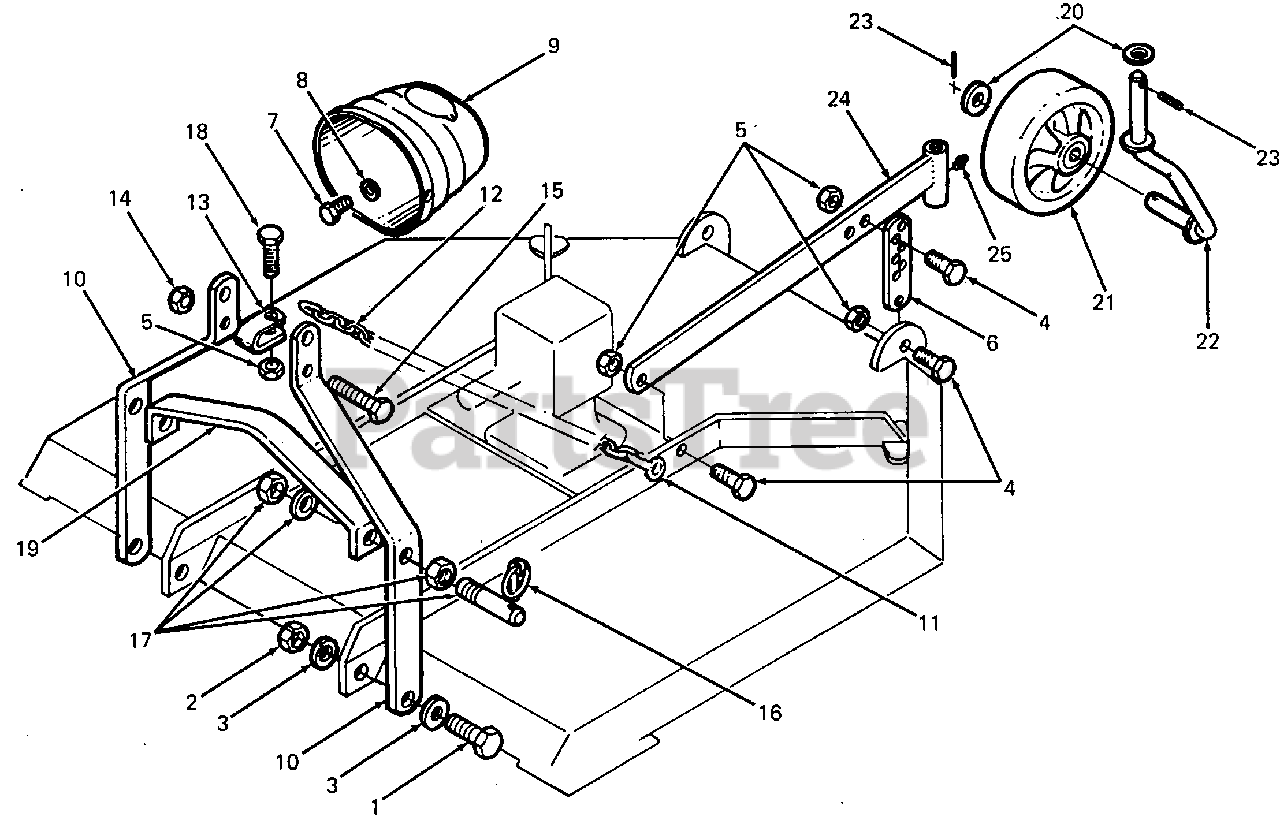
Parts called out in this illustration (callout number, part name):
1	Capscrew, 5/8 X 1-1/2"
2	Locknut, 5/8
3	Flatwasher, 5/8
4	Capscrew, 3/8 X 1-1/4"
5	Locknut, 3/8
6	Strap, Adjusting
7	Capscrew, M8 X 15 mm
8	Flatwasher, M8
10	Mast Half
11	Shackle, Chain
14	Locknut, 1/2
15	Capscrew, 3/8 X 1-1/4"
16	Pin, Lynch
17	Pin, Adjustable Lift
18	Capscrew, 3/8 X 1-1/4"
19	Brace, Cross
20	Flatwasher, 3/4
21	Tire Assy
22	Caster Leg
23	Pin, Roll, 3/16 X 1-1/4"
24	Arm, Caster
25	Grease Fitting
